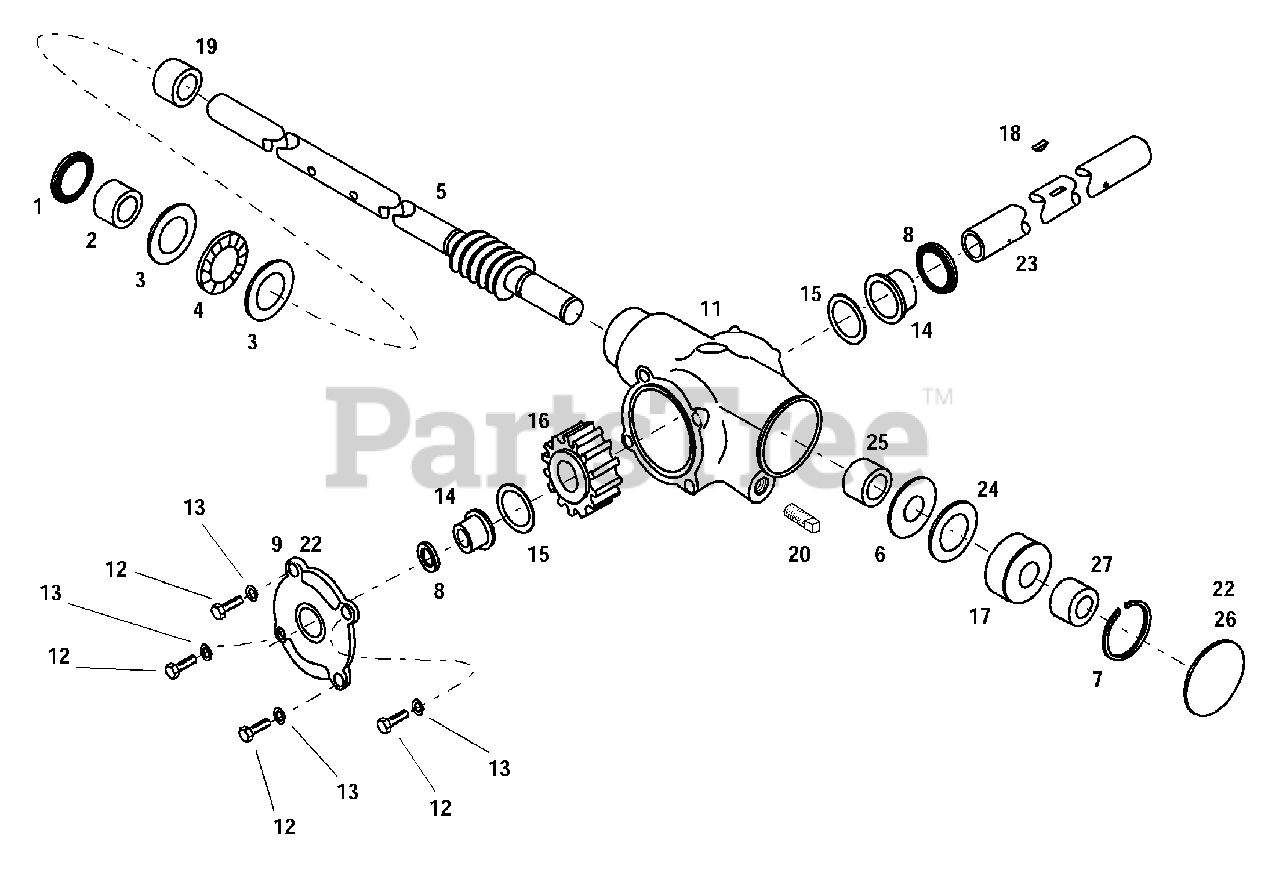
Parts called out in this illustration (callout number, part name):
2	Needle Bearing
3	Thrust Race
4	Roller Thrust Bearing
5	Impeller Shaft
6	Washer
7	Internal Retaining Ring
8	Oil Seal
9	Flanged Cover
11	Gear Case
12	Hex Hd. Cap Screw, 1/4-20 x 5/8
13	Lock Washer, 1/4
14	Flange Bearing
15	Thrust Race
16	Worm Gear, 20T
17	Spacer
18	Woodruff Key, 1/4 x 7/8
20	Square Head Plug, 1/4-18 NPT
22	Sealant
23	Auger Shaft
24	Thrust Race
25	Spacer
26	Welch Plug
27	Needle Bearing
101	Gear Lube, EP 90, 8 oz.
